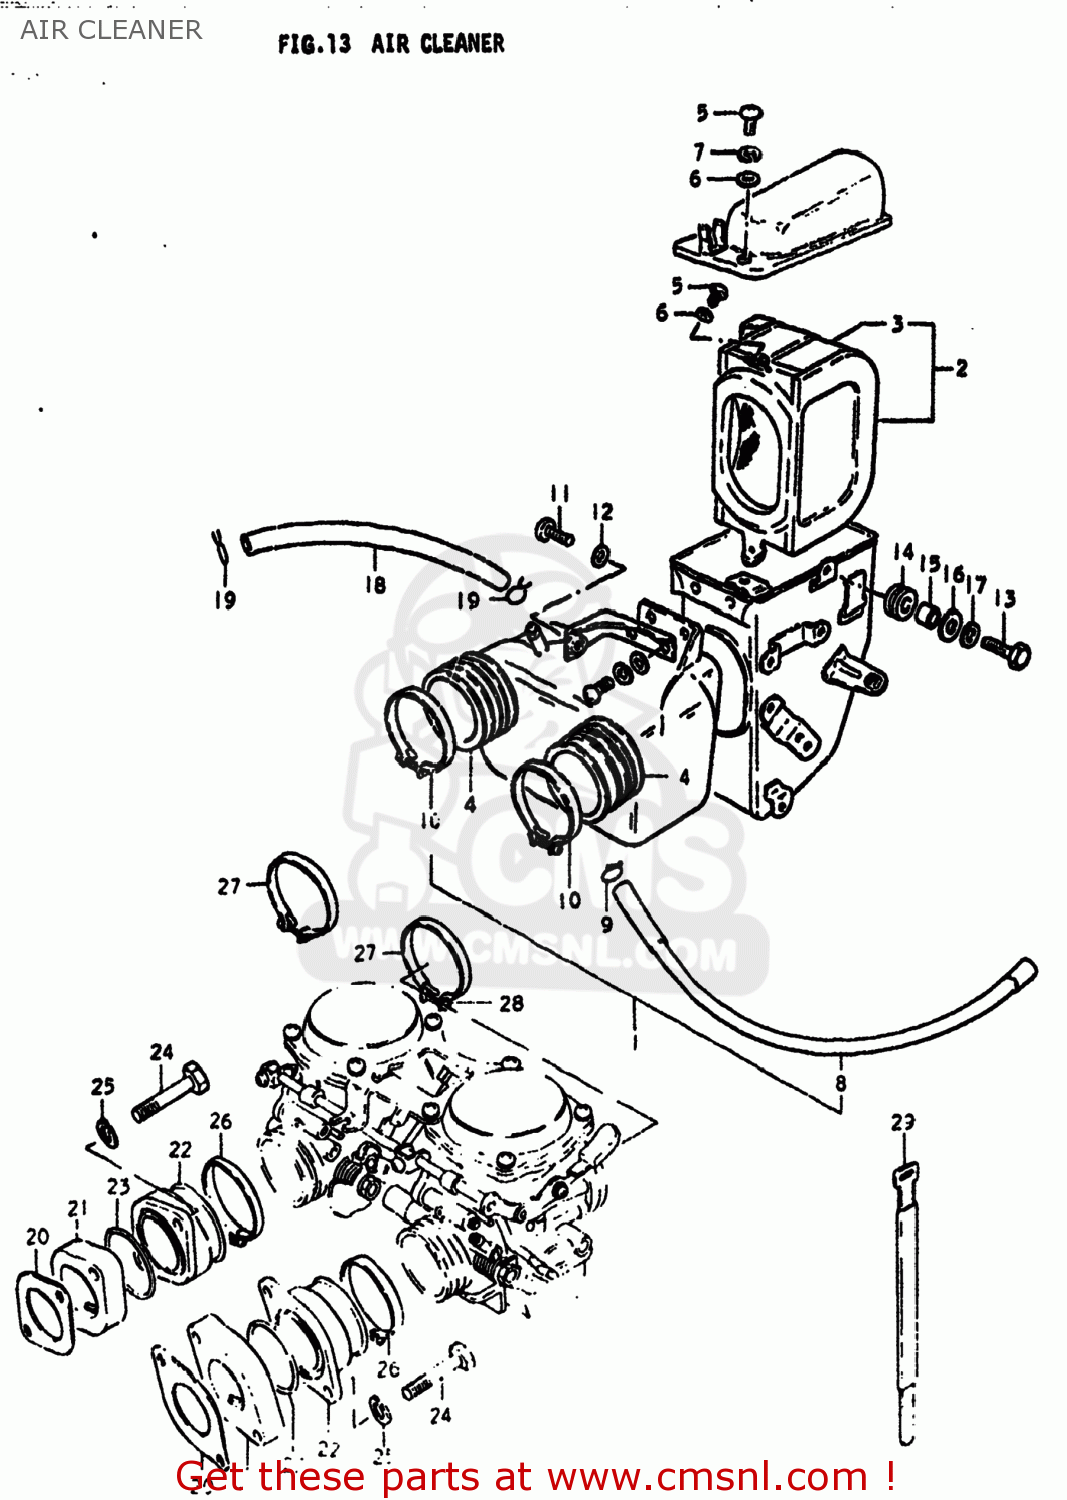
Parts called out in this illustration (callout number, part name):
1	CLEANER ASSEMBLY,AIR
2	FILTER ASSY
3	FILTER
4	HOSE,AIR CLEANER INLET
5	SCREW
6	WASHER
7	LOCK WASHER
8	HOLDER,FILTER
9	HOSE,AIR CLEANER
10	CLAMP
11	SCREW
12	WASHER 6MM
13	BOLT
14	CUSHION
15	SPACER (6.1X9X9)
16	WASHER
17	LOCK WASHER
18	HOSE
19	CLIP
20	GASKET,CARBURETOR (NAS)
21	INSULATOR,CARBURETOR
22	PIPE,INTAKE
23	O-RING (D:2.4 ID:39.7)
24	BOLT
25	LOCK WASHER
26	CLAMP
27	CLAMP
28	SCREW
29	CLAMP
